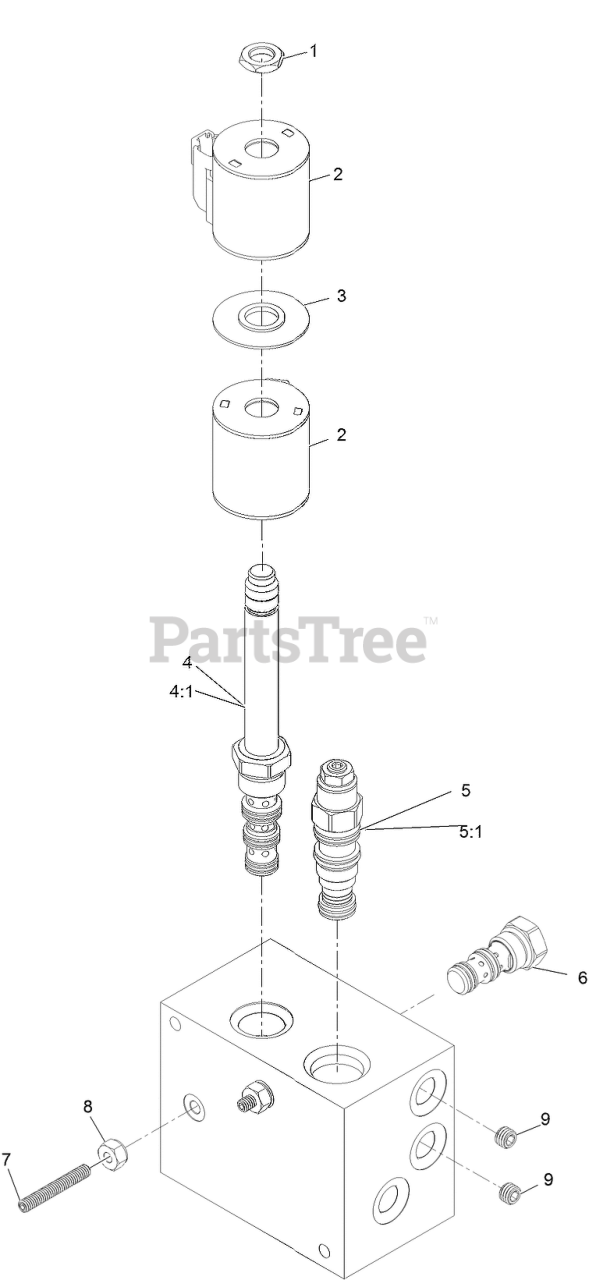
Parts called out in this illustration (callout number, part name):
1	NUT-COIL
2	COIL-12V
3	Spacer-E Coil
4	Solenoid Valve ASM
4:1	SPOOL VALVE SEAL KIT
5	VALVE-COUNTERBALANCE
5:1	Seal Kit
6	Valve-Check, Po
7	SCREW-SET
8	Nut-Sealing, Hex
9	Plug-Orifice (0.020)
